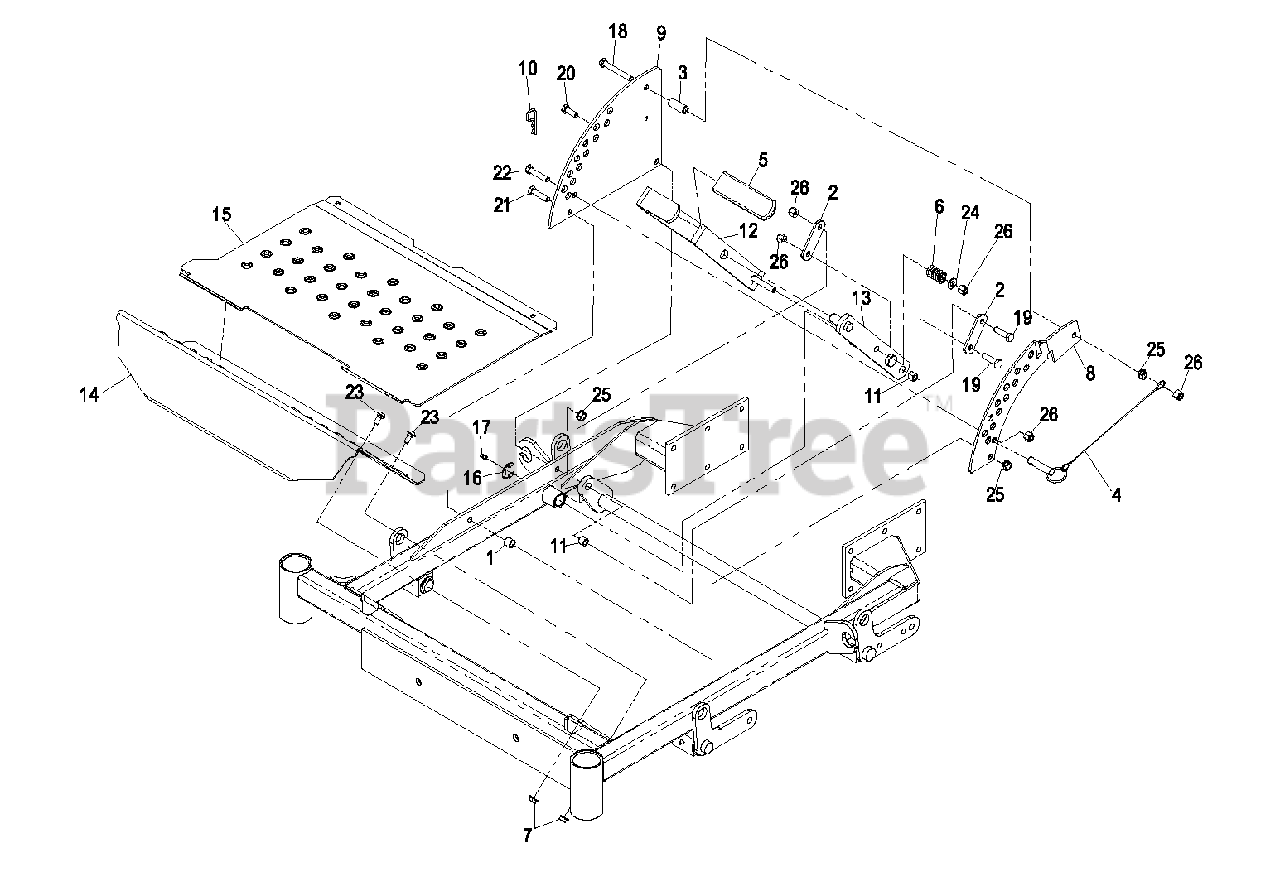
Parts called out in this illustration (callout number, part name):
1	BUSHING-LEVER, LIFT
2	ARM-LIFT, DECK
3	BUSHING-LEVER, LIFT
4	PIN-HITCH (W/LANYARD)
5	GRIP-LEVER, LIFT
6	SPRING-COMPRESSION
8	PLATE-LIFT, DECK W/DECAL
9	PLATE-LIFT, DECK
10	PIN-COTTER
11	BUSHING
12	ASM, LIFT LEVER / GRIP
13	WLD, DECK LIFT ARM-LHP
15	ASM,FLOORPAN
16	RING-RETAINING, EXT
17	FITTING-GREASE
18	SCREW-HH
19	SCREW-HH
20	SCREW-HH
21	SCREW-HH
22	SCREW-HH
23	BOLT-CARR
24	WASHER-FLAT
25	NUT-HHF, WHIZ
26	NUT-LOCK, NI
